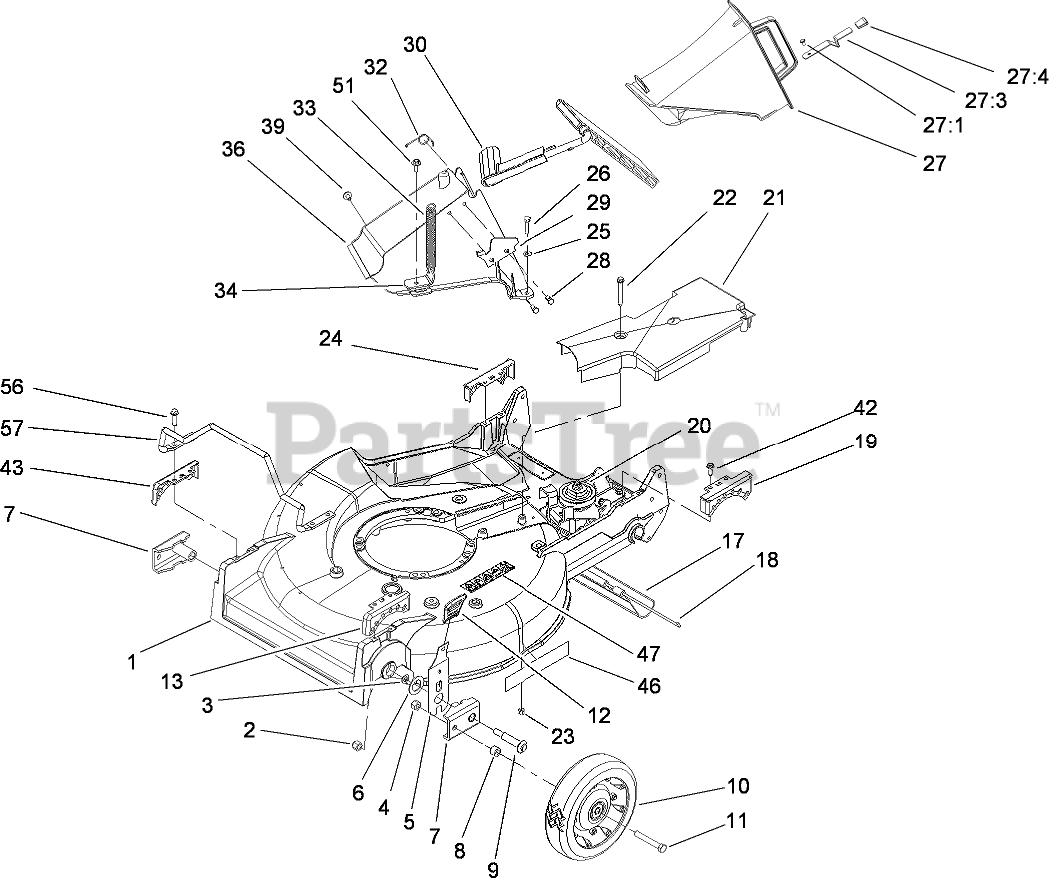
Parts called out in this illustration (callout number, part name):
1	HOUSING
2	NUT-LOCK
3	WASHER
4	NUT-LOCK, CONE
5	SPRING ARM ASM
6	WASHER-THRUST
7	ARM-PIVOT, FRONT
8	SPACER-WHEEL
9	SCREW-SHOULDER
10	Wheel and Tire ASM
11	SCREW-HH
12	KNOB-HOC
13	QUADRANT-FRONT, LH
17	SHIELD-TRAILING
18	ROD-SHIELD
19	QUADRANT-REAR, LH
20	GEAR CASE ASM
21	COVER-BELT
22	SCREW-HHFTF
23	NUT-LOCK, NI
24	QUADRANT-REAR, RH
25	WASHER-FLAT
26	SCREW-HH
27	DISCHARGE PLUG ASM
27:1	RIVET-HEAD, FLAT
27:3	LATCH-PLUG, DISCHARGE
27:4	GRIP-LATCH
28	SCREW-PLASTITE
29	LATCH-PLATE
30	DISCHARGE DOOR ASM
32	RETAINER-DOOR
33	SPRING-DOOR
34	BRACKET-SPRING
36	TUNNEL-DISCHARGE
39	SCREW AND WASHER ASM
42	SCREW-HWHTF
43	QUADRANT-FRONT, RH
47	DECAL-DANGER
51	SCREW-HWH
56	SCREW-HWHTF
57	GUARD-ENGINE
